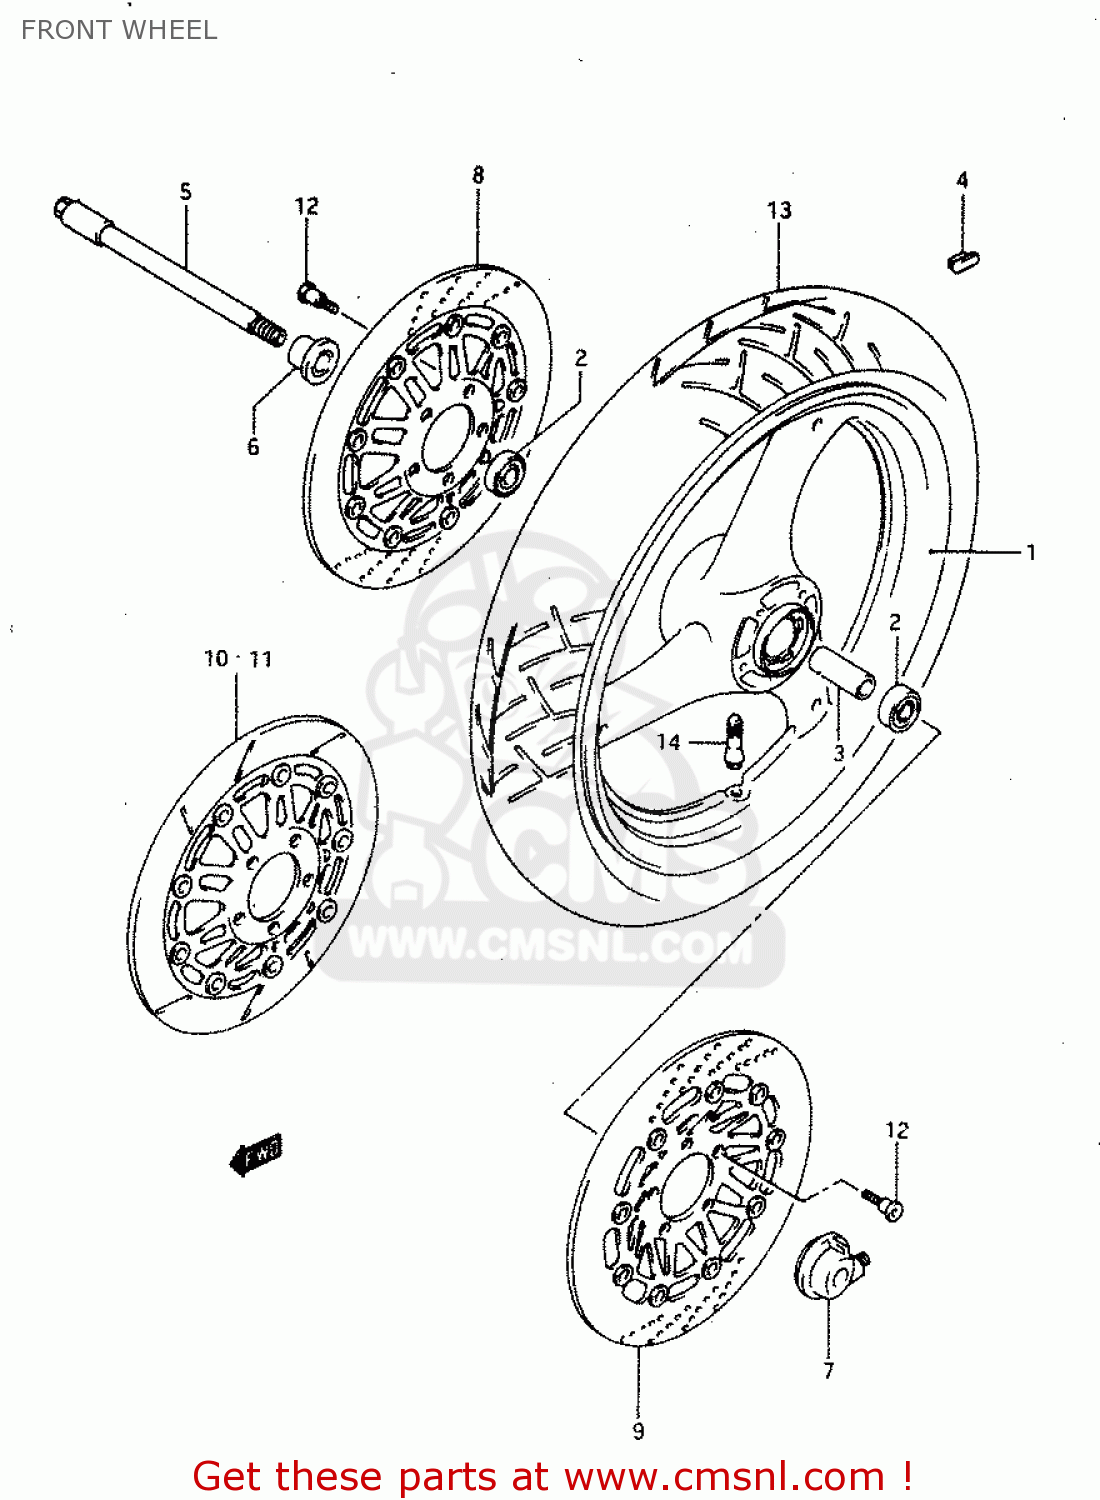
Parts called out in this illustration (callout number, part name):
1	WHEEL,FR(MT3.00X17)
2	BEARING
3	SPACER(17.5X22.5X73)
4	BALANCER,WHEEL
5	AXLE,FR
6	SPACER,FR AXLE,R
7	BOX ASSY,SPEEDOMETER GEAR
8	DISC,FR BRAKE,R
9	DISC,FR BRAKE,L
10	DISC, FRONT BRAKE RH (GOLD/BLACK)
11	DISC, FRONT BRAKE LH (GOLD/BLACK)
12	BOLT 8X33
13	TIRE, FRONT (110/70 R17 54H) (BRIDGESTON
14	VALVE ASSEMBLY,WHEEL,TR412
